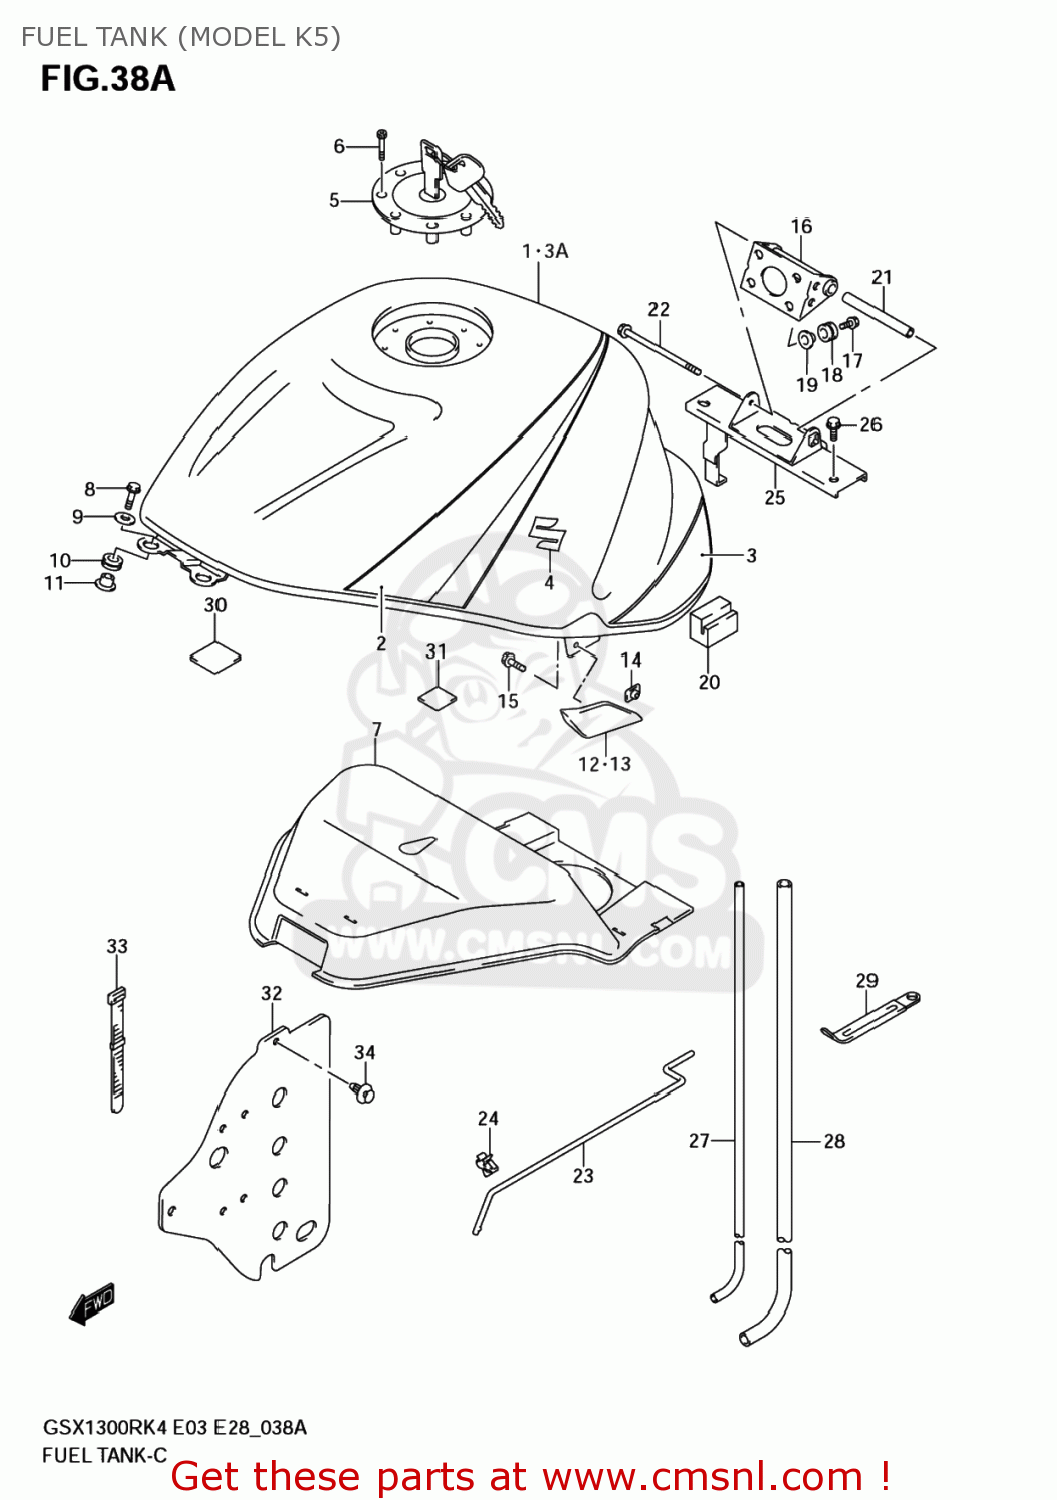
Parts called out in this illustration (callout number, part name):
1	TANK ASSY,FUEL(GRAY)
2	TAPE SET,FUEL TANK
3	TAPE SET,FUEL TANK LWR
3A	TANK ASSY,FUEL(GRAY)
4	EMBLEM,S
5	CAP SET,FUEL TANK
6	BOLT(5X20)
7	SHIELD,FUEL TANK HEAT
8	SCREW(6X25)
9	WASHER(6.5X18X1.5)
10	CUSHION
11	WASHER
12	COVER,FUEL TANK SIDE,R
13	COVER,FUEL TANK SIDE,L
14	PLATE,FUEL TANK SIDE
15	SCREW 6X10
16	BRACKET,FUEL TANK RR NO.1
17	BOLT(6X20)
18	CUSHION
19	WASHER
20	CUSHION,FUEL TANK SIDE
21	SPACER,FUEL TANK RR
22	BOLT
23	STAY,FUEL TANK
24	CLAMP
25	BRACKET,FUEL TANK RR NO.2
26	BOLT
27	HOSE,FUELTANK BREATHER
28	HOSE(7X11X600)
29	CLAMP(L:80)
30	CUSHION
31	CUSHION,FUEL TANK COVER
32	SHEET,HEAT SHIELD RUBBER
33	CLAMP(L:165)
34	CLIP(BLACK)
